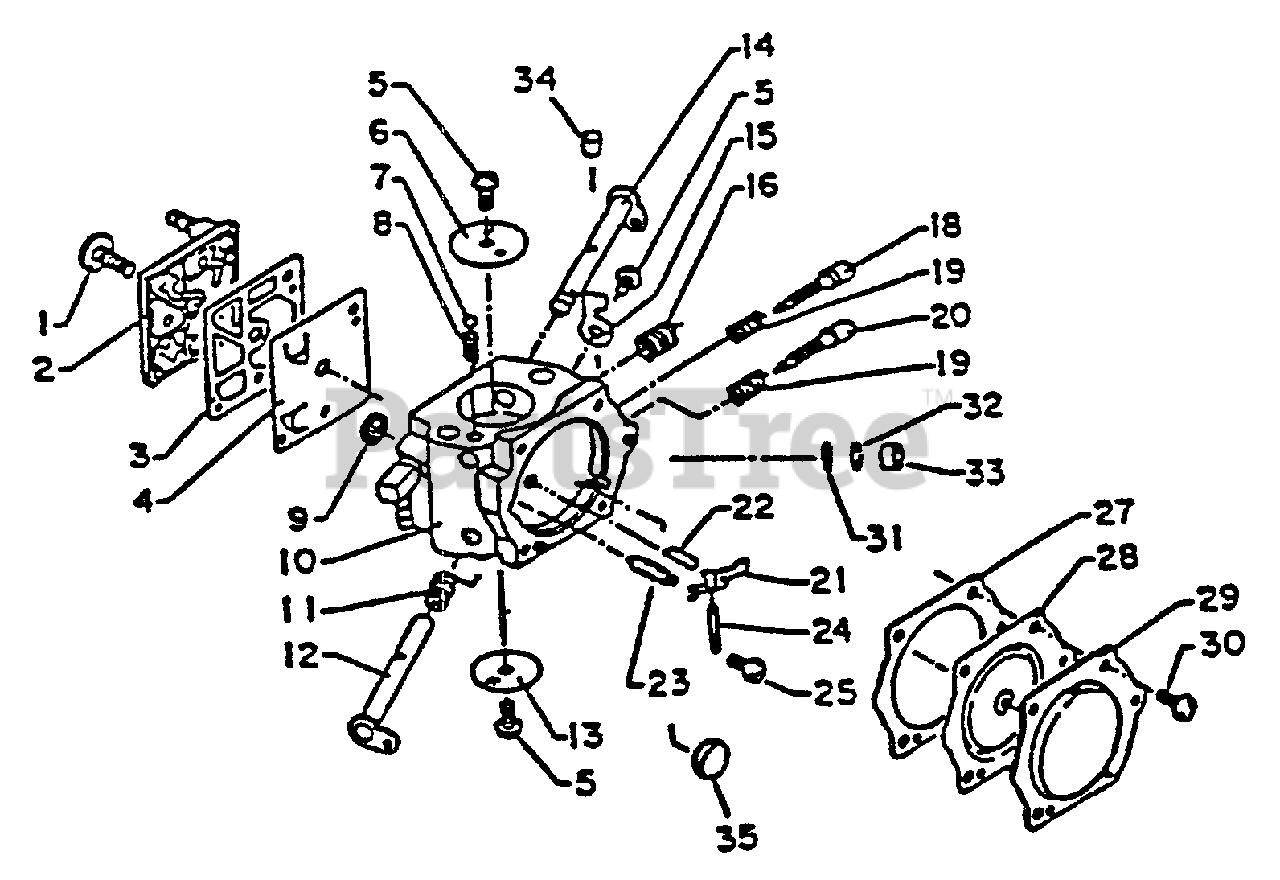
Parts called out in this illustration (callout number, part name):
2	COVER, FUEL PUMP
3	GASKET, PUMP
4	DIAPHRAGM, PUMP
6	VALVE, CHOKE
7	BALL, CHOKE FRICTION
9	STRAINER
10	REPAIR KIT, CARBURETOR
11	SPRING, THROTTLE RETURN
12	SHAFT, THROTTLE
13	VALVE, THROTTLE
14	SHAFT, CHOKE
15	STOP, THROTTLE
16	SPRING, IDLE ADJUST
18	NEEDLE, IDLE
20	NEEDLE, HIGH SPEED
21	LEVER, METERING
22	SPRING, METERING LEVER
23	VALVE, INLET NEEDLE
24	PIN, METERING LEVER
25	SCREW
27	GASKET, METERING
28	DIAPHRAGM, METERING
29	COVER, METERING DIAPHRAGM
30	SCREW
31	STRAINER
32	RING, RETAINING
33	PLUG, WELCH
34	PLUG, FRICTION
35	PLUG, WELCH
